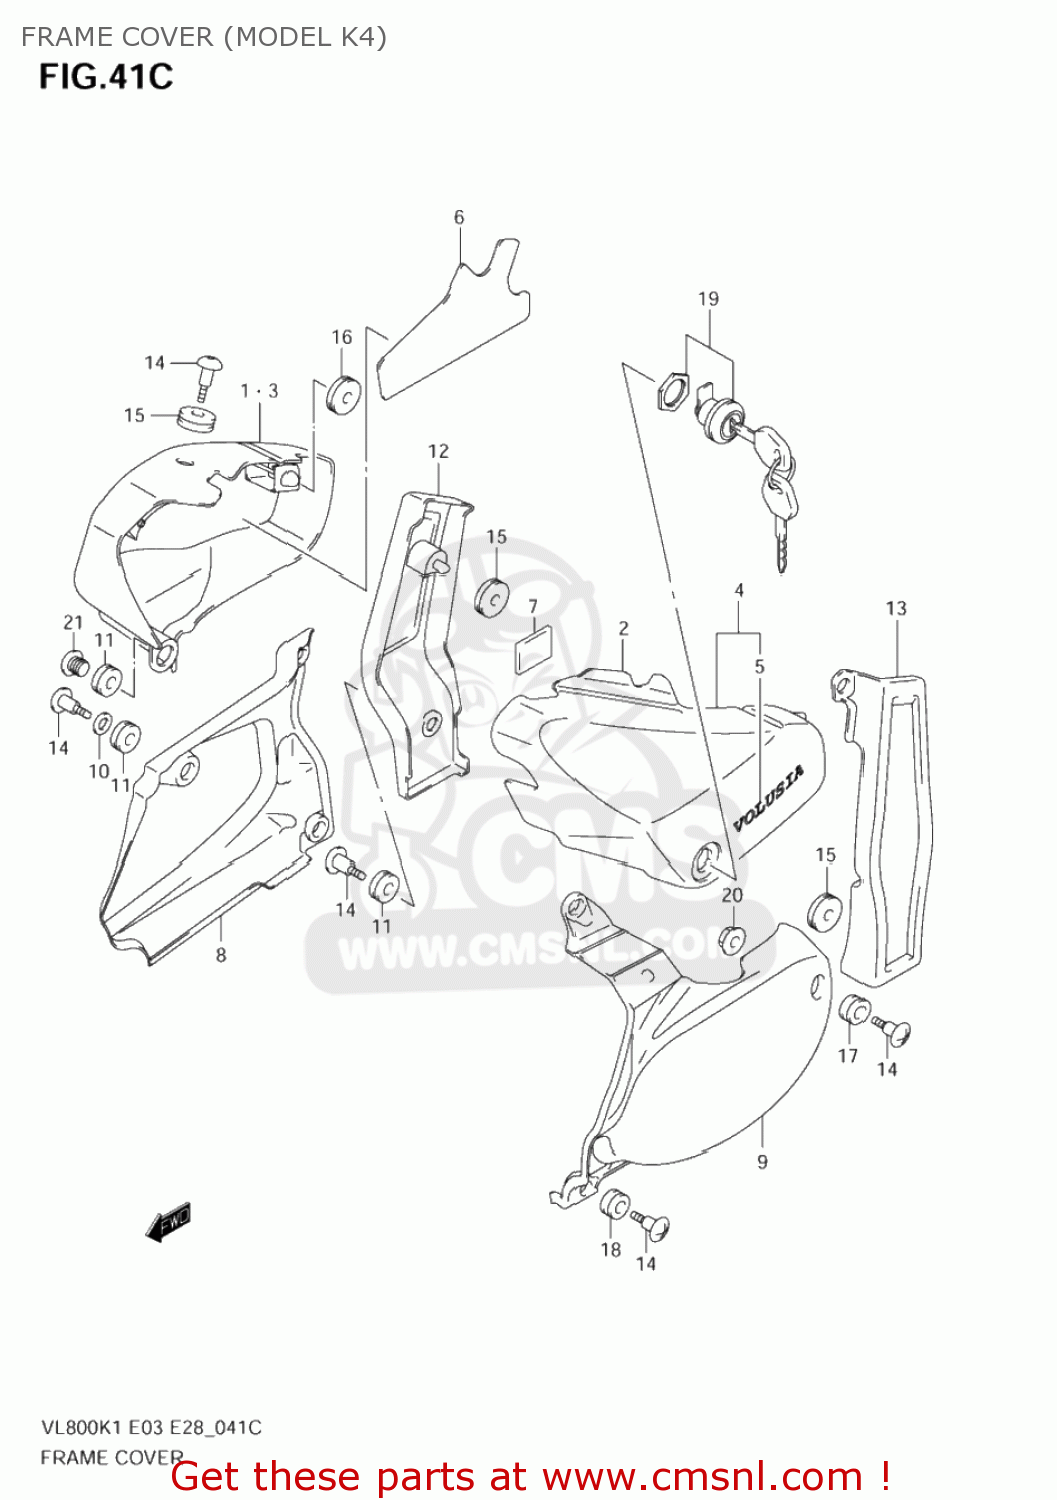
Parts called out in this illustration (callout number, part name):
1	COVER,SIDE,R(BLUE)
2	COVER,SIDE,L
3	COVER,SIDE,R(GRAY)
4	COVER,SIDE,L(GRAY)
5	EMBLEM,FRAME COVER
6	SHIELD,FRAME COVER
7	PAD,BALANCER UPPER,R
8	COVER,SIDE LWR,R
9	COVER,SIDE LWR,L
10	WASHER(10.5X20X2.3)
11	CUSHION
12	COVER SIDE,REA
13	COVER,SIDE RR,L
14	SCREW(6X20)
15	CUSHION
16	CUSHION
17	CUSHION
18	CUSHION
19	LOCK SET,COVER
20	NUT
21	CAP(OD:14)
